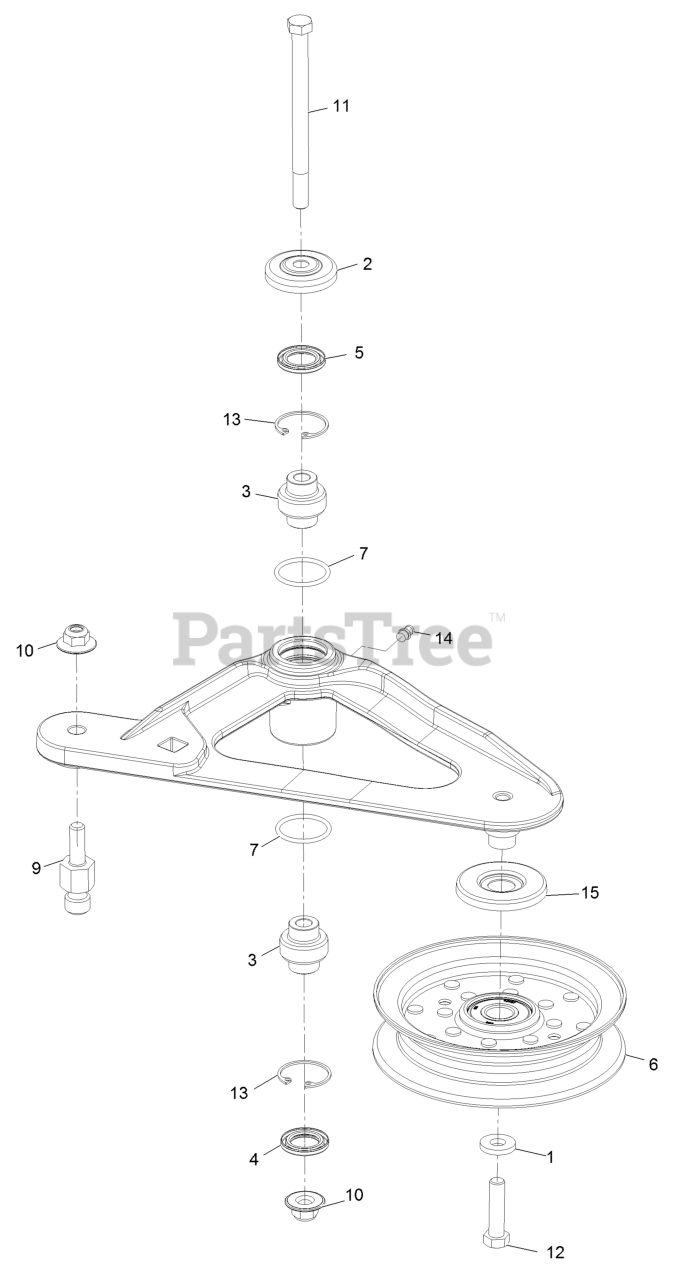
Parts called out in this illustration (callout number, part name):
2	Guard-Top
3	Bearing-Spherical
4	Seal-Double Lip
5	Seal-Lip, Single
6	Idler-Pulley, Flat 5.00X0.87
9	Pin-Spring, Anchor
10	Nut-Flange, NI
11	Screw-Shoulder, HH
12	Screw-HH
13	Ring-Snap
14	Fitting-Grease
15	Guard-Dust Shield
